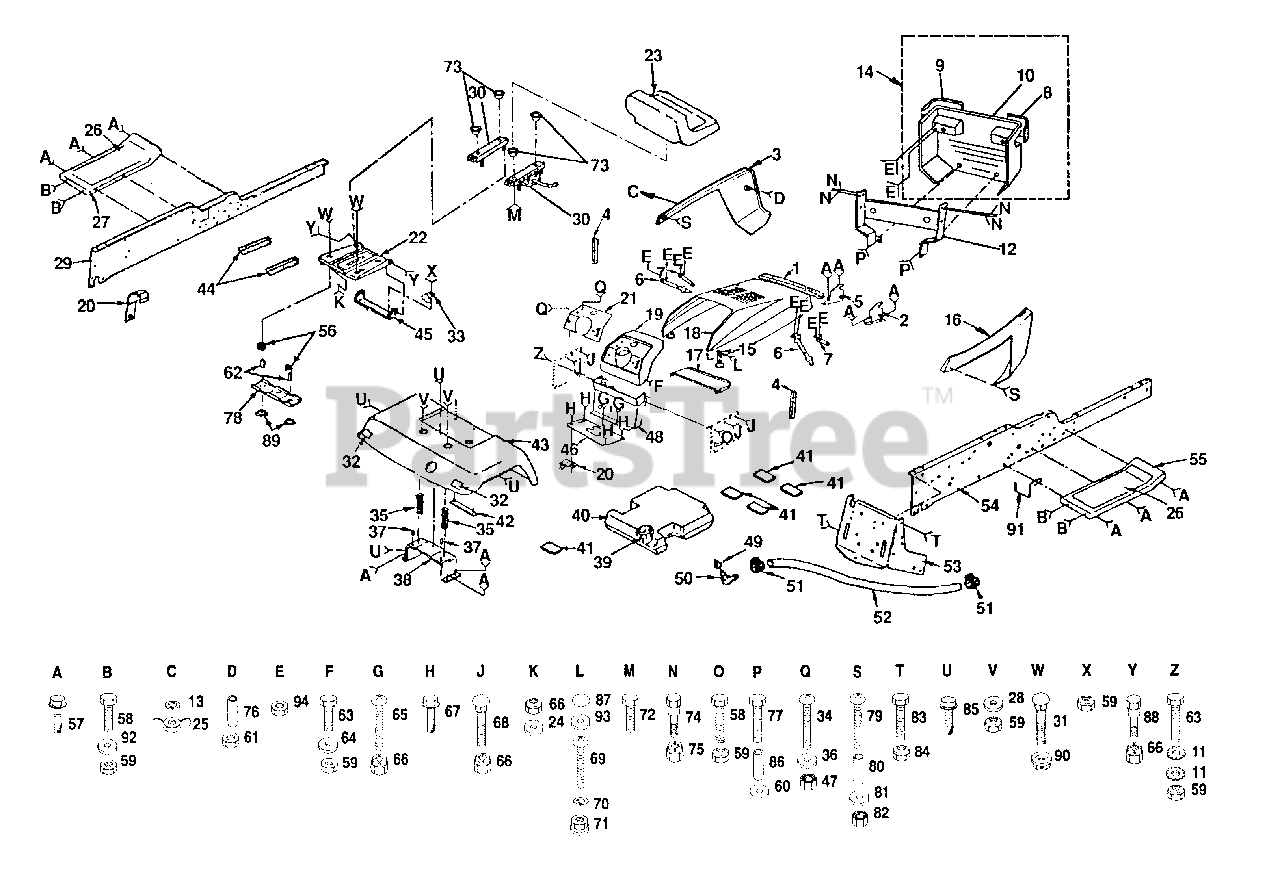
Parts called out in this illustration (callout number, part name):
1	Strip, Foam
2	Frame, Pivot, Ass'y, Bracket, R.H.
3	Panel, Side, L.H.
4	Strip, Foam
5	Frame, Pivot, Ass'y, Bracket, L.H.
6	Strap Assembly, Hinge, Rear
7	Strap Assembly, Hinge, Front
8	Lens,R.H.
9	Lens, L.H.
10	Grill
11	Washer, Lock Ext. Tooth 3/8
12	Support, Grill
13	Washer, Lock 1/4
14	Grill, Assembly
15	Latch, Hood
16	Panel, Side, R.H.
17	Support, Battery
18	Hood
19	Dashboard
20	Clip, Insulated
21	Dashplate
23	Seat
24	Washer 11/32 x 1 x 10 Gauge
25	Nut, Wing 1/4-20
26	Pad, Footrest
27	Footrest, L.H.
28	Washer 13/32 x 1 x 14 Gauge
29	Rail, Frame, L.H.
30	Slide, Seat Set
31	Bolt, Carriage 1/4-20 x 1-1/4
32	Reflector, Taillight
33	Clip, Insulated
34	Screw, Mach. Hd. 5/16-18 x 3/4
35	Spring, Compression
36	Washer 11/32 x 11/16 x 16 Gauge
38	Bracket, Fender
39	Cap, Fuel
40	Tank, Fuel w/sensor
41	Pad, Spacer
42	Strap, Fender
43	Fender
44	Foam, Strip
45	Bracket, Pivot, Seat
46	Cover, Shift, Gate
47	Nut, Keps 5/16-18
48	Dash Assembly
49	Bushing
50	Stem, Tank Fuel
51	Clamp, Hose
52	Fuel Line
53	Drawbar
54	Rail, Frame, R.H.
55	Footrest, R.H.
56	Spring, Compression
57	Screw, Hex Washer Thread Rolling 3/8-16 x 3/4
58	Bolt, Hex 3/8-16 x 3/4
59	Locknut 3/8-16
60	Washer 9/32 x 3/4 x 16 Ga.
61	Nut, Hex 1/4-20
62	Spacer, Split
63	Bolt, Hex 3/8-16 x 1
64	Washer 13/32 x 13/16 x 16 Gauge
65	Screw, Mach. Cr. Thrd. 5/16-18 x 3/4
66	Nut, Crownlock 5/16-18
67	Screw, Hex Washer Thrd. Cutting 1/4-20 x 1/2
68	Bolt, Carriage 5/16-18 x 3/4
69	Screw, Cr. Pan. Mach. #10-24 x 1/2
70	Washer, Lock #10
71	Nut, Weld
72	Screw, Hex 5/16-18 x 1
74	Bolt, Shoulder 1/4-20
75	Nut, Crownlock 1/4-20
77	Bolt, Fin Hex 1/4-20 x 2-1/2
78	Bracket, Switch Mount
79	Screw, Mach Cr. Pan #10-24 x 1-1/4
80	Spacer, Split #10 x 3/4
81	Washer 7/32 x 1/2 x 18 Gauge
82	Nut, Keps #10-24
83	Bolt, Hex 7/16-14 x 1
84	Locknut 7/16-14
85	Screw, Hex Washer Thread Rolling 3/8 x 16 x 1/2
88	Bolt, Shoulder
89	Bushing, Snap
90	Nut, Flange Lock 1/4-20
91	Retainer, Belt, Lower
92	Washer 13/32 x 13/16 x 17 Gauge
93	Washer, Snap Cap
94	Nut, Hex 1/4-20
